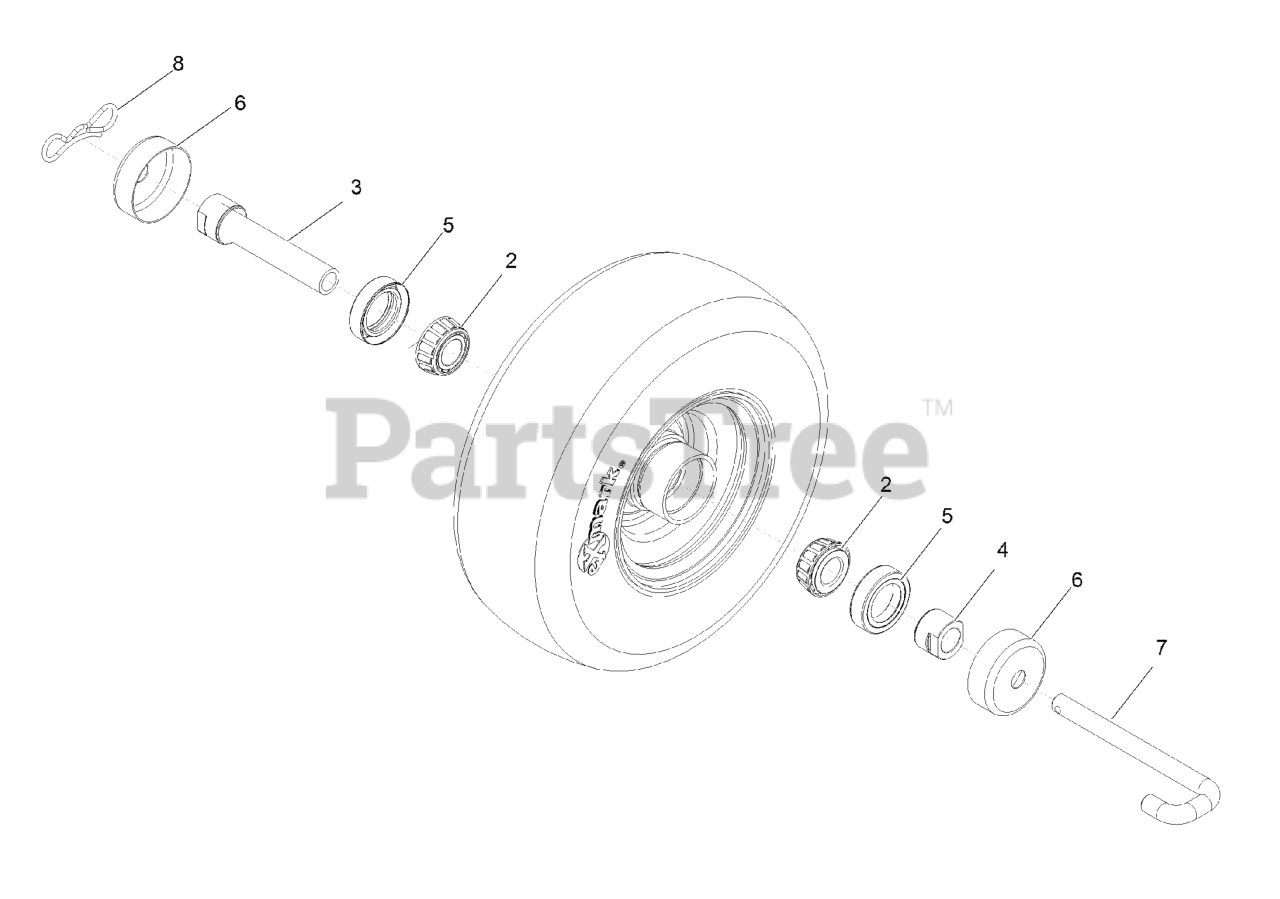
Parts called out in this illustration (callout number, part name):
2	BEARING-CONE, TAPERED ROLLER
3	CASTER AXLE ASM
4	SPACER-NUT
5	SEAL-CASTER
6	GUARD-SEAL
7	PIN, CASTER
8	PIN-COTTER, LOCKING
